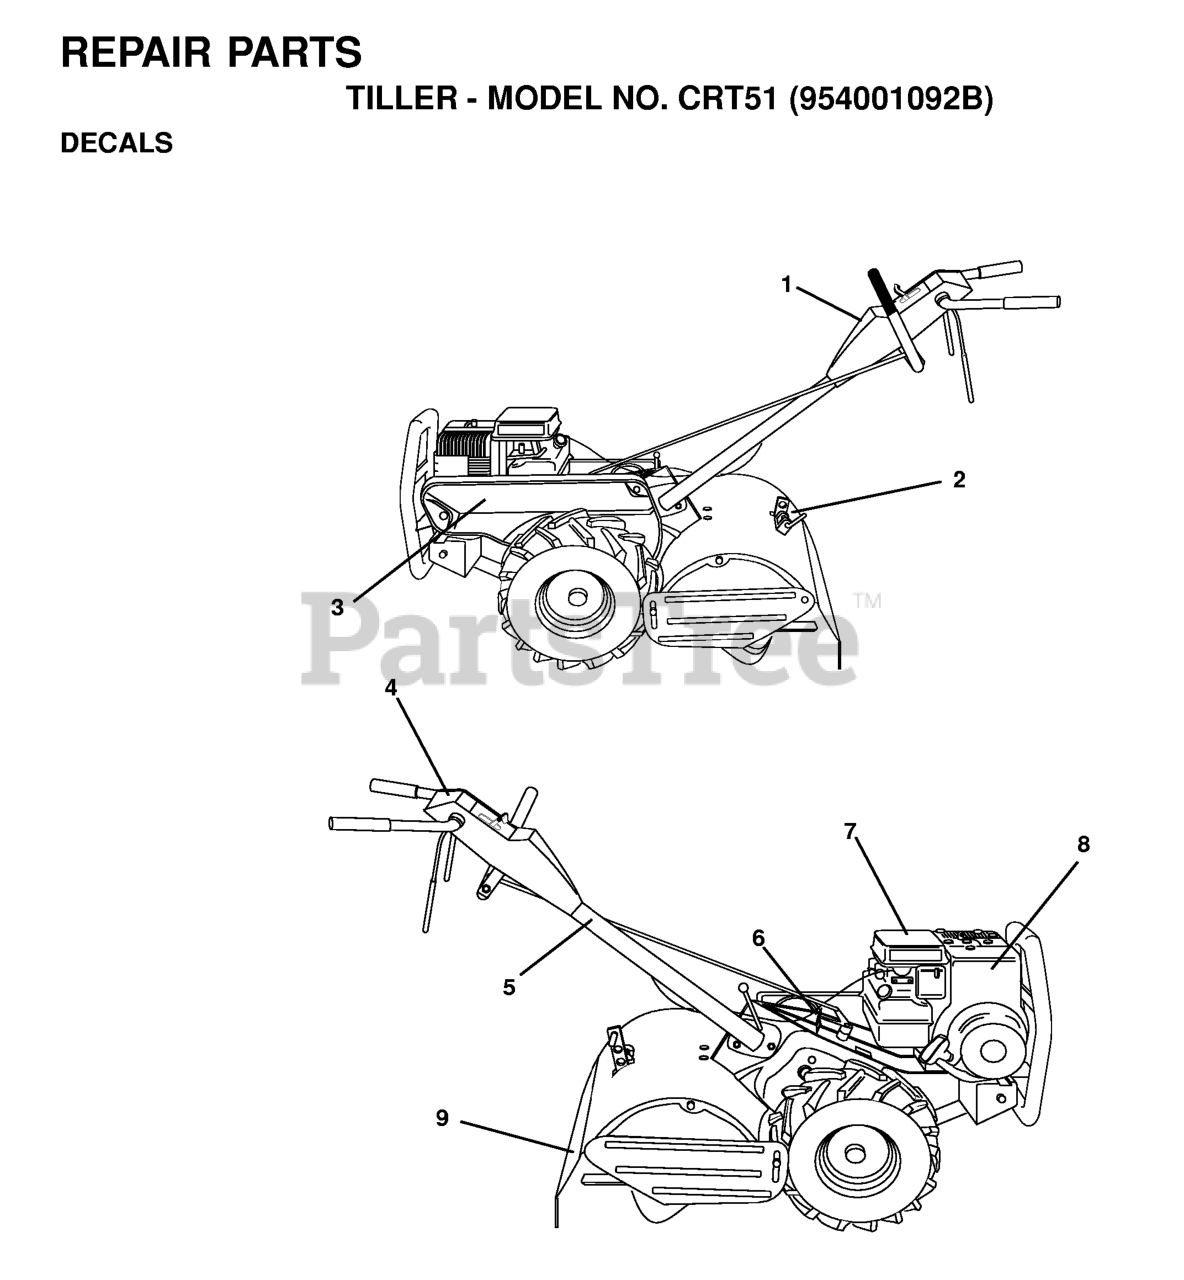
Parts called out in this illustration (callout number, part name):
2	DECAL.AUGER."
3	DECAL.CHUTE.SAFETY.
4	DECAL.AUGER.SAFETY.
5	DECAL CONSOLE DECAL DECAL.SNOW
6	DECAL CONSOLE DECAL DECAL.SNOW
7	DECAL.BELT.GUARD.
